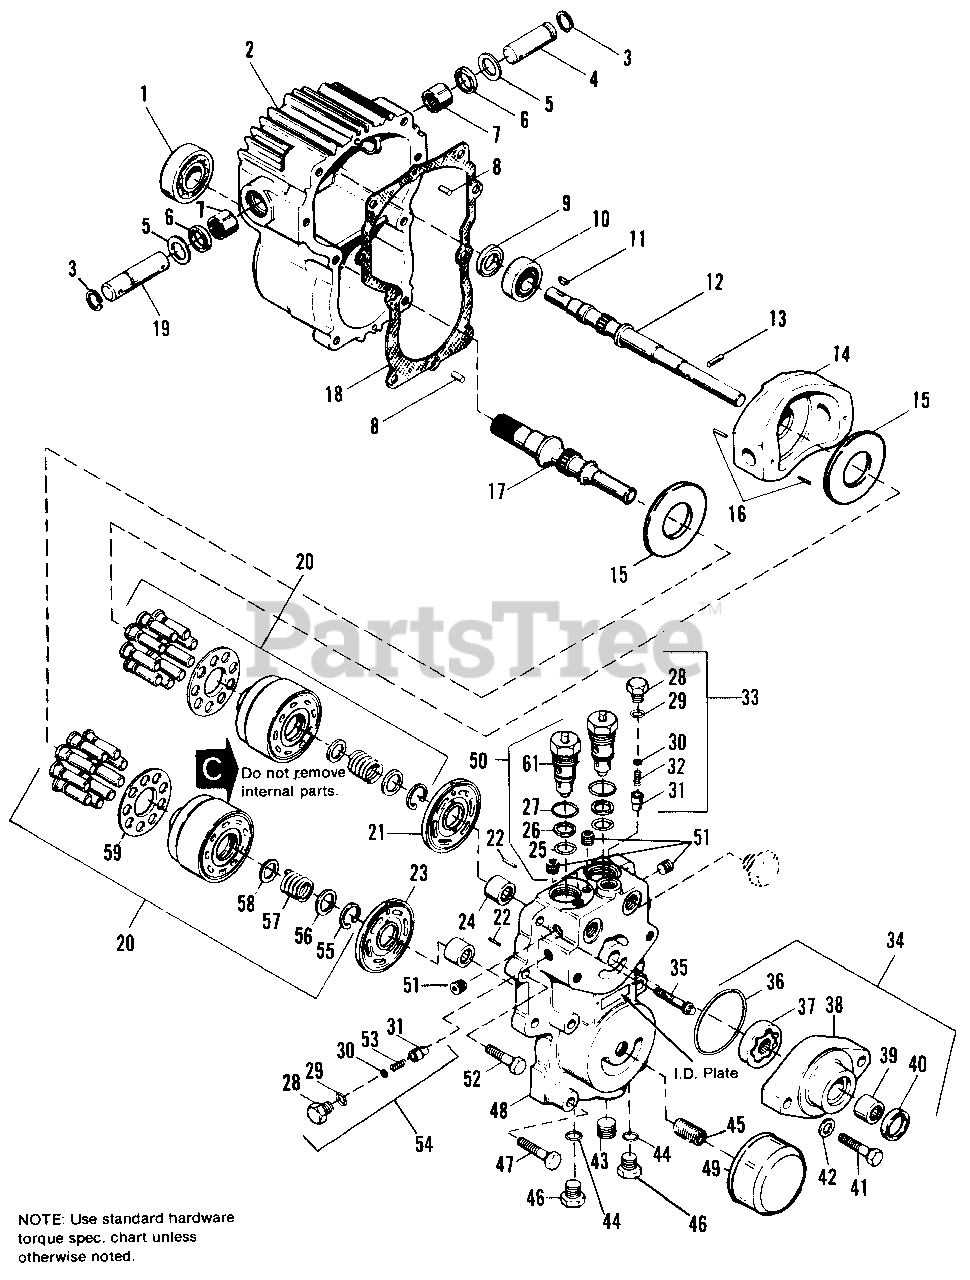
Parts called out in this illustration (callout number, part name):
1	BEARING, Ball
3	RING, Retainer
5	WASHER, Special
7	BEARING, Needle
8	PIN, Headless, Straight
10	BEARING, Ball
11	KEY, Woodruff
12	SHAFT, Pump
13	PIN, Headless
14	PLATE, Swash
15	PLATE, Thrust
16	PIN, Spring, Coiled
17	SHAFT, Motor
20	CYLINDER BLOCK KIT
21	PLATE, Valve, Pump
22	PIN, Straight
23	PLATE, Valve, Motor
24	BEARING, Needle
26	RING, Backup
28	PLUG, Hex Hd.
30	SHIM (Shim as required)
31	CONE, Relief Valve
32	SPRING, Relief Valve
33	RELIEF VALVE KIT (Incl. Ref. Nos. 28-32)
34	CHARGE PUMP KIT (Incl. Ref. Nos. 36-40)
35	CAPSCREW, 12 pt.
39	BEARING, Needle
41	CAPSCREW, 7/16-14 x 2
42	WASHER, Flat
45	UNION, Filter
46	PLUG, Hex Hd.
47	CAPSCREW, 3/8-16 x 2
48	SECTION, Center
49	FILTER, 25 Micron
50	CHECK VALVE (Incl. Ref. Nos. 25, 26 & 27)
52	CAPSCREW, 3/8-16 x 1-1/4
53	SPRING, Relief
54	RELIEF VALVE KIT (Incl. Ref. Nos. 28-31 & 53)
55	RING, Retaining
56	WASHER, Rear
58	WASHER, Front
59	RETAINER, Hub
60	HOUSING ASSY. (Incl. Ref. Nos. 1, 2, 6, 7 & 9)
61	CHECK VALVE ASSY.
